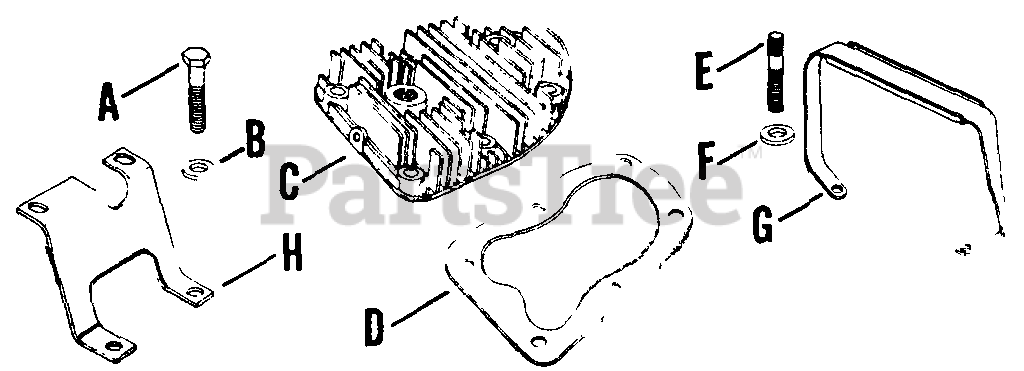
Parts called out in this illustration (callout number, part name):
A	SCREW - (#DSC)
A	SCREW - USE 41 086 02
B	WASHER, FLAT 5/16"
C	HEAD - (#DSC)
